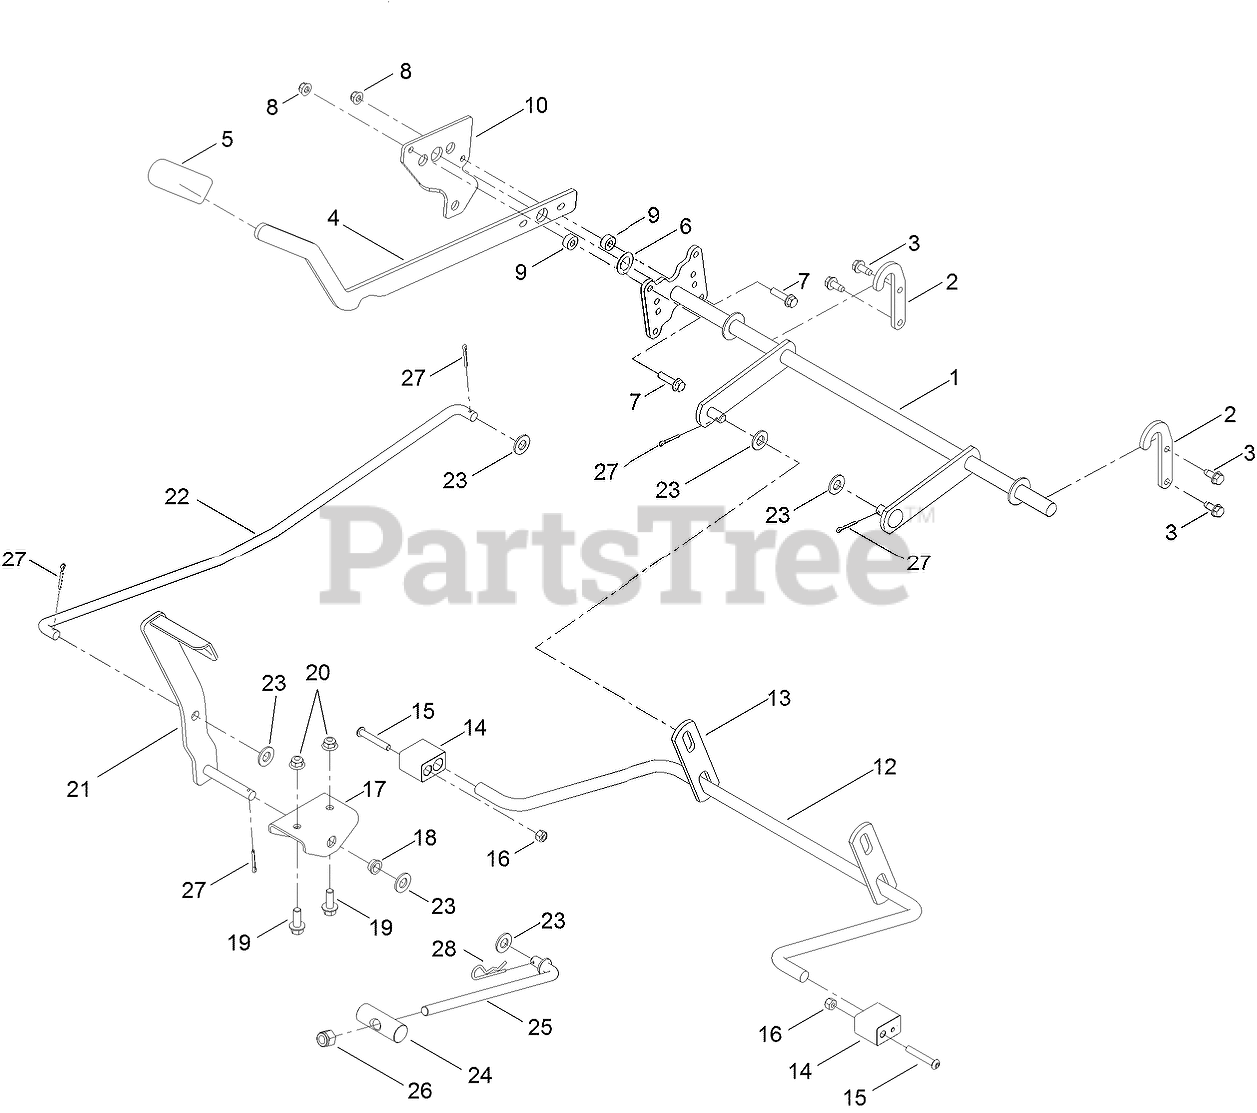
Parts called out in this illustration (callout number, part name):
1	LIFT-DECK, WIDE
2	BRACKET-LIFT
3	SCREW-HWHTF
4	LEVER-LIFT
5	GRIP-LEVER
6	WASHER-THRUST
7	SCREW-HHF
8	NUT-HF, NI
9	SPACER
10	PLATE-FOOTLIFT
12	ARM-LIFT, REAR (WIDE)
13	LINK-LIFT
14	BLOCK-PIVOT
15	SCREW-HSBH
16	NUT-LOCK, NI
17	BRACKET-FOOTLIFT
18	BUSHING-FLANGE
19	SCREW-HHF
20	NUT-HF, NI
21	PEDAL ASM
22	ROD-FOOTLIFT
23	WASHER-FLAT
24	PIN-PIVOT
25	ROD-MOUNT, DECK
26	NUT-HEX
27	PIN-COTTER
28	PIN-COTTER
